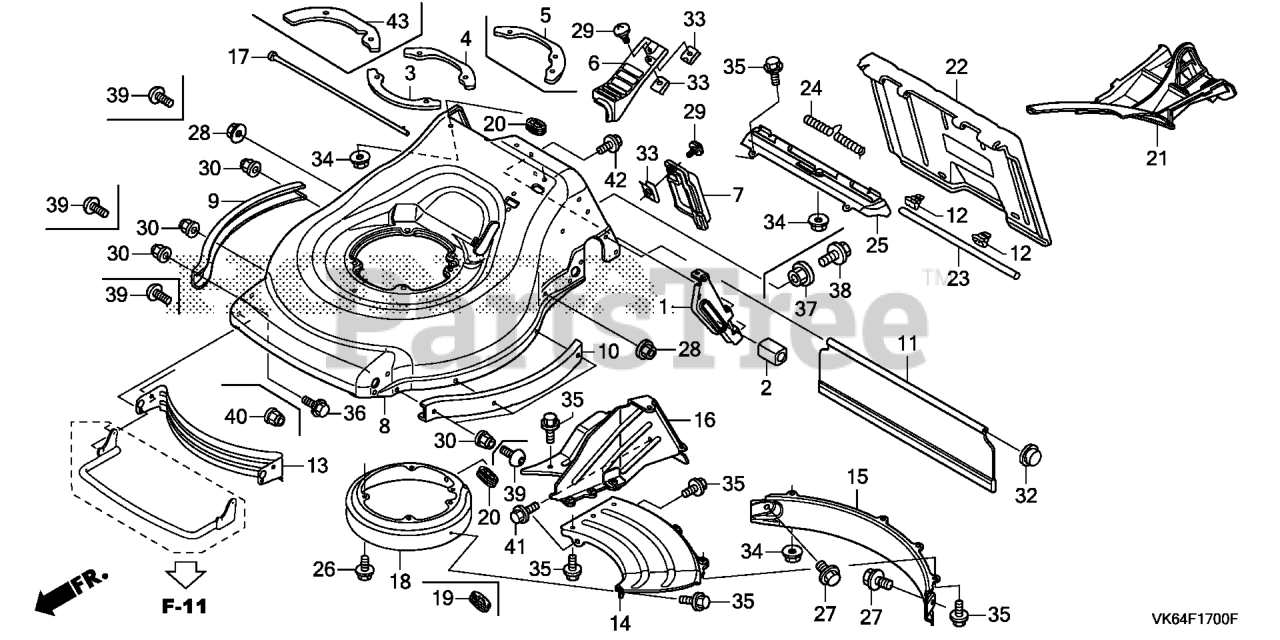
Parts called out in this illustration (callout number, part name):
3	SPACER, ENGINE (A)
5	SPACER, ENGINE (B)
8	HOUSING, CUTTER *NH190M* (VINTAGE GRAY METALLIC)
9	GUARD, R. HOUSING
10	GUARD, L. HOUSING
11	SHIELD, RR.
12	STOPPER, DISCHARGE GUARD
13	SCROLL, FR.
14	SCROLL, RR. (UPPER)
15	SCROLL, RR. (LOWER)
16	SCROLL, DISCHARGE
17	SHAFT, RR. SHIELD
18	COVER, ROTO-STOP
19	GROMMET, CABLE
21	STUFFING *NH105* (MAT BLACK)
22	GUARD, DISCHARGE
23	SHAFT, DISCHARGE GUARD
24	SPRING, GUARD RETURN
25	PLATE, GRASS BAG
26	BOLT, ENGINE SETTING
26	BOLT, FLANGE (5/16-24X1")
27	BOLT, SPECIAL
28	NUT, SELF-LOCK (8MM)
28	NUT, FLANGE (8MM)
30	NUT, NYLON RING (6MM)
32	NUT, PUSH (6.35MM)
34	NUT, FLANGE (6MM)
35	BOLT, FLANGE (6X12) Use up to Engine SN 1543277.
37	NUT, FLANGE (10MM)
38	BOLT, FLANGE (10X16)
39	SCREW, HEX. SOCKET BUTTON (6X12)
39	SCREW (6X12)
40	NUT, NYLON RING (6MM)
41	BOLT, FLANGE (6X12) Use up to Engine SN 1543277.
41	BOLT, FLANGE (6X10)
